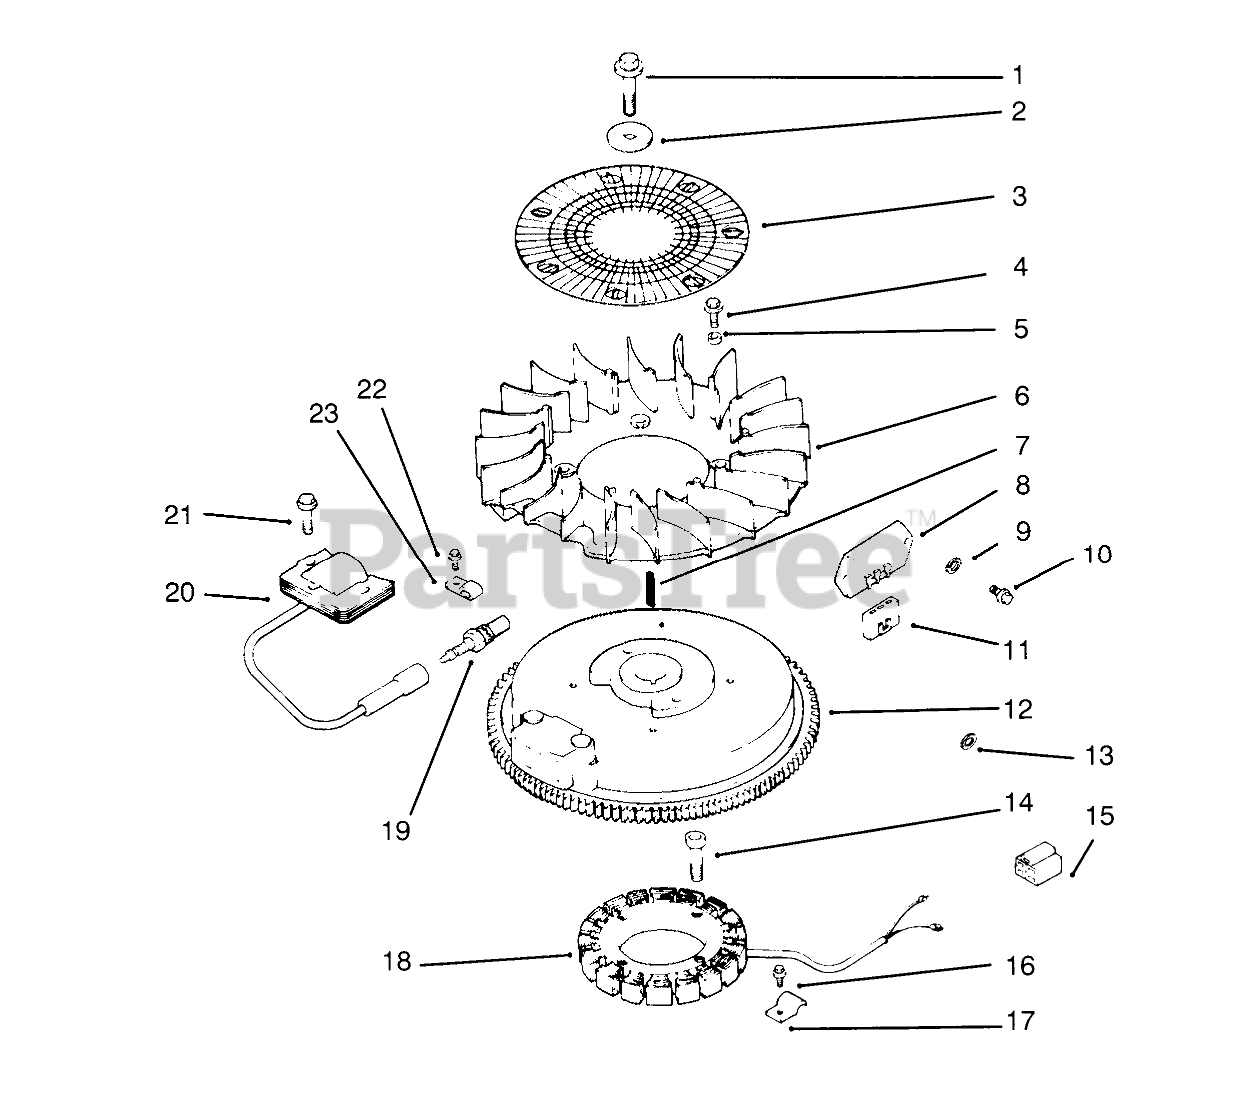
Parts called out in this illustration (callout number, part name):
1	Screw-Flywheel Mounting (Only On: 72042,72043,72062,72063)
2	Washer-Flywheel Screw (Only On: 72042,72043,72062,72063)
3	Screen-Grass (Only On: 72042,72043,72062,72063)
4	Screw M6x1.0x16 (Only On: 72042,72043,72062,72063)
5	Spacer-Fan (Only On: 72042,72043,72062,72063)
6	Fan (Only On: 72042,72043,72062,72063)
7	Key (Only On: 72042,72043,72062,72063)
8	Rectifier-Regulator (Only On: 72042,72043,72062,72063)
9	Washer-Lock (Only On: 72042,72043,72062,72063)
10	Screw M6x1.0x16 (Only On: 72042,72043,72062,72063)
11	Connector-Regulator (Only On: 72042,72043,72062,72063)
12	Flywheel ASM (Only On: 72042,72043,72062,72063)
13	Washer-Flat (Only On: 72042,72043,72062,72063)
14	Screw M5x0.8x25 (Only On: 72042,72043,72062,72063)
15	Connector-5 Contact (Only On: 72042,72043,72062,72063)
16	Screw M5x0.8x10 (Only On: 72042,72043,72062,72063)
17	Clip-Stator Harness (Only On: 72042,72043,72062,72063)
18	Stator-15 Amp (Only On: 72042,72043,72062,72063)
19	Spark Plug (Only On: 72042,72043,72062,72063)
20	Module-Ignition (Only On: 72042,72043,72062,72063)
21	Screw M5x0.8x20 (Only On: 72042,72043,72062,72063)
22	Screw M5x0.8x10 (Only On: 72042,72043,72062,72063)
23	Clip-Kill Lead (Only On: 72042,72043,72062,72063)
